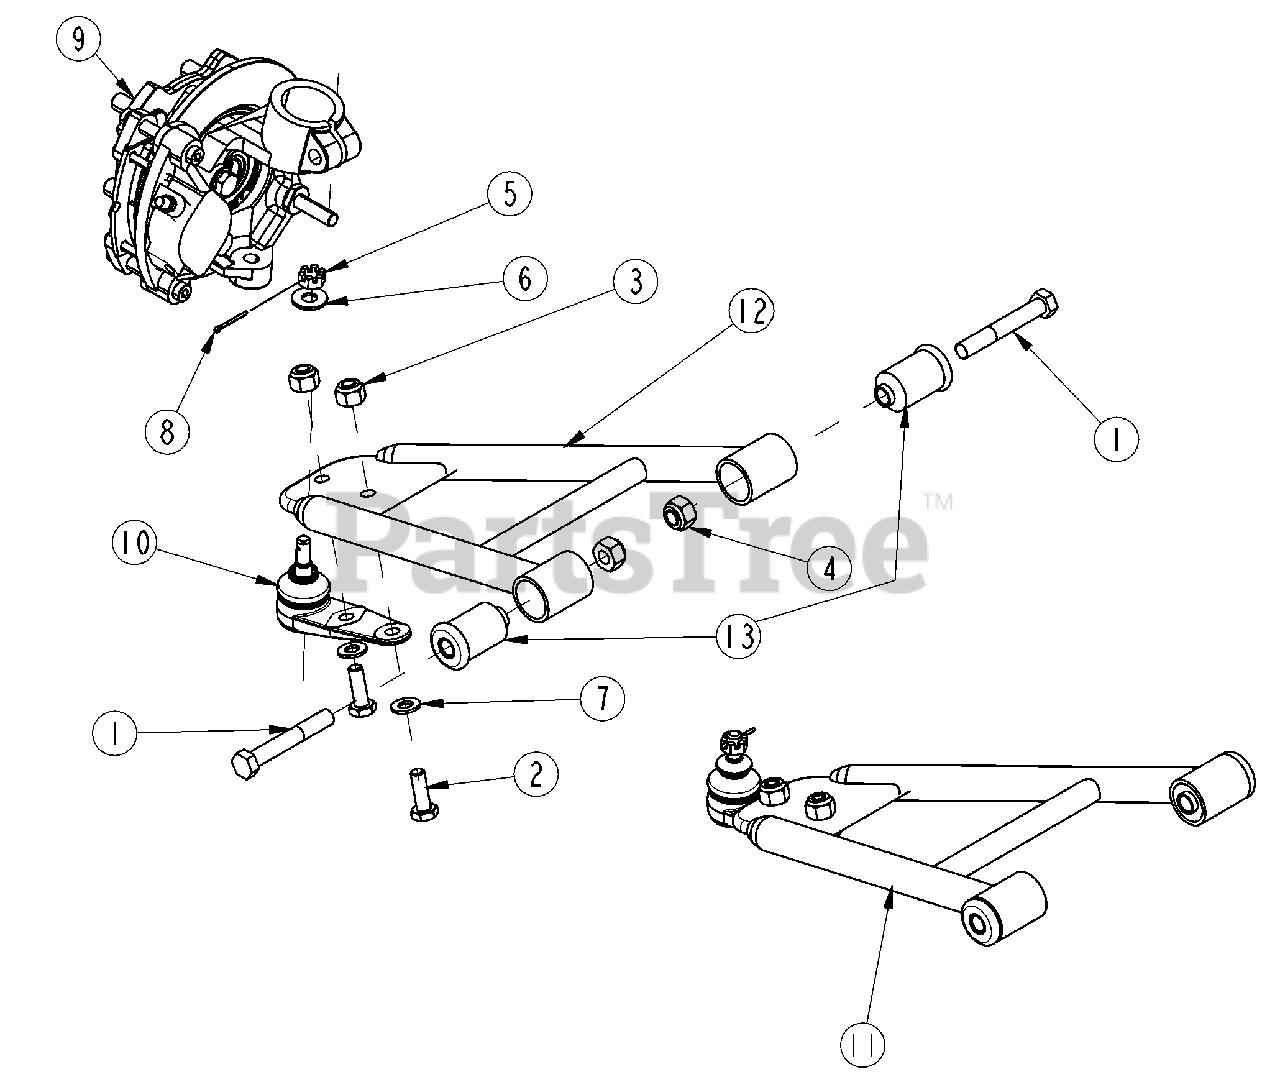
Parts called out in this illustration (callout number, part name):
1	HHCS M12X1.75X80 GR8.8 PLT
2	BOLT, M10X1.50X30 HEX 8.8 Y
3	NUT-LK-NYL M10-1.5 YWZC
4	@NUT-LK-NYL M12-1.75 YWZC
5	NUT-HEX-SLOTTED M10-1.25 YWZC
6	@WSHR-FL-STL.438X1.00X.083 YWZ
7	WSHR-FL-STL M10 10.5X20X2 YWZC
8	@PIN-CTR .09X1.00 EXTPRSQCT YZ
9	RH DISC BRAKE ASM 172MM W/JNT
10	BALL JOINT BOLT ON SIR
11	CONTROL ARM ASM, LH
12	CONTROL ARM WLDT, LH
13	BUSHING, A-ARM
